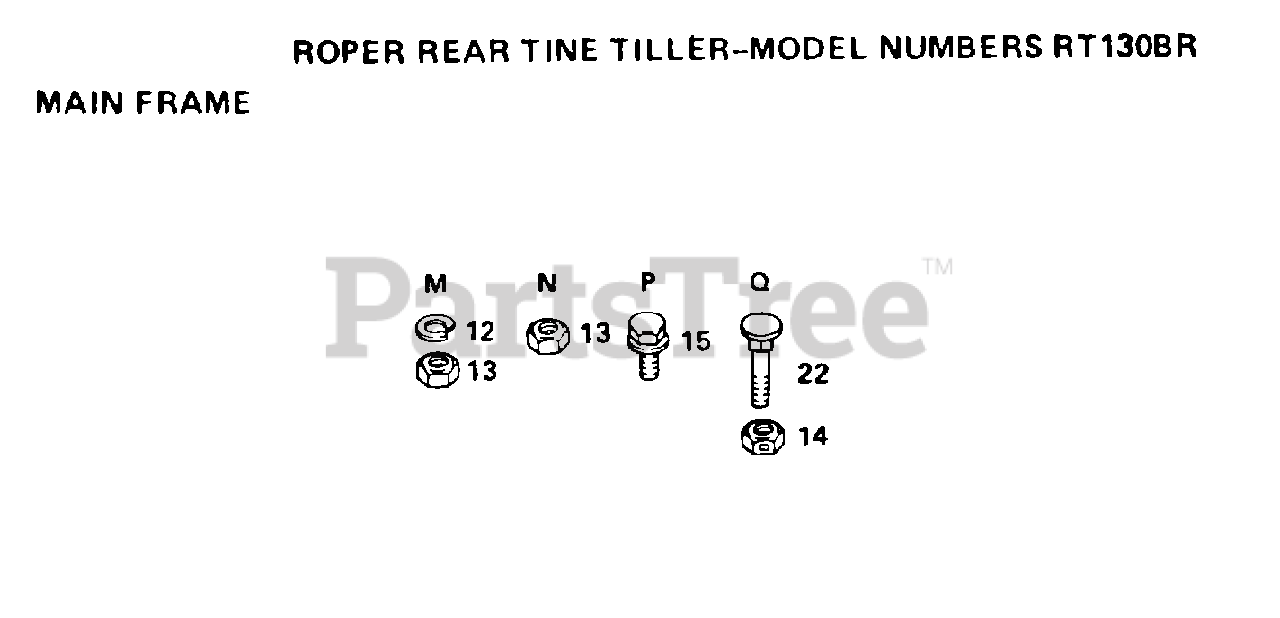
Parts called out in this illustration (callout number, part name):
12	LOCKWASHER
13	NUT.HEX.3/8-16UNC
15	SCREW TI
